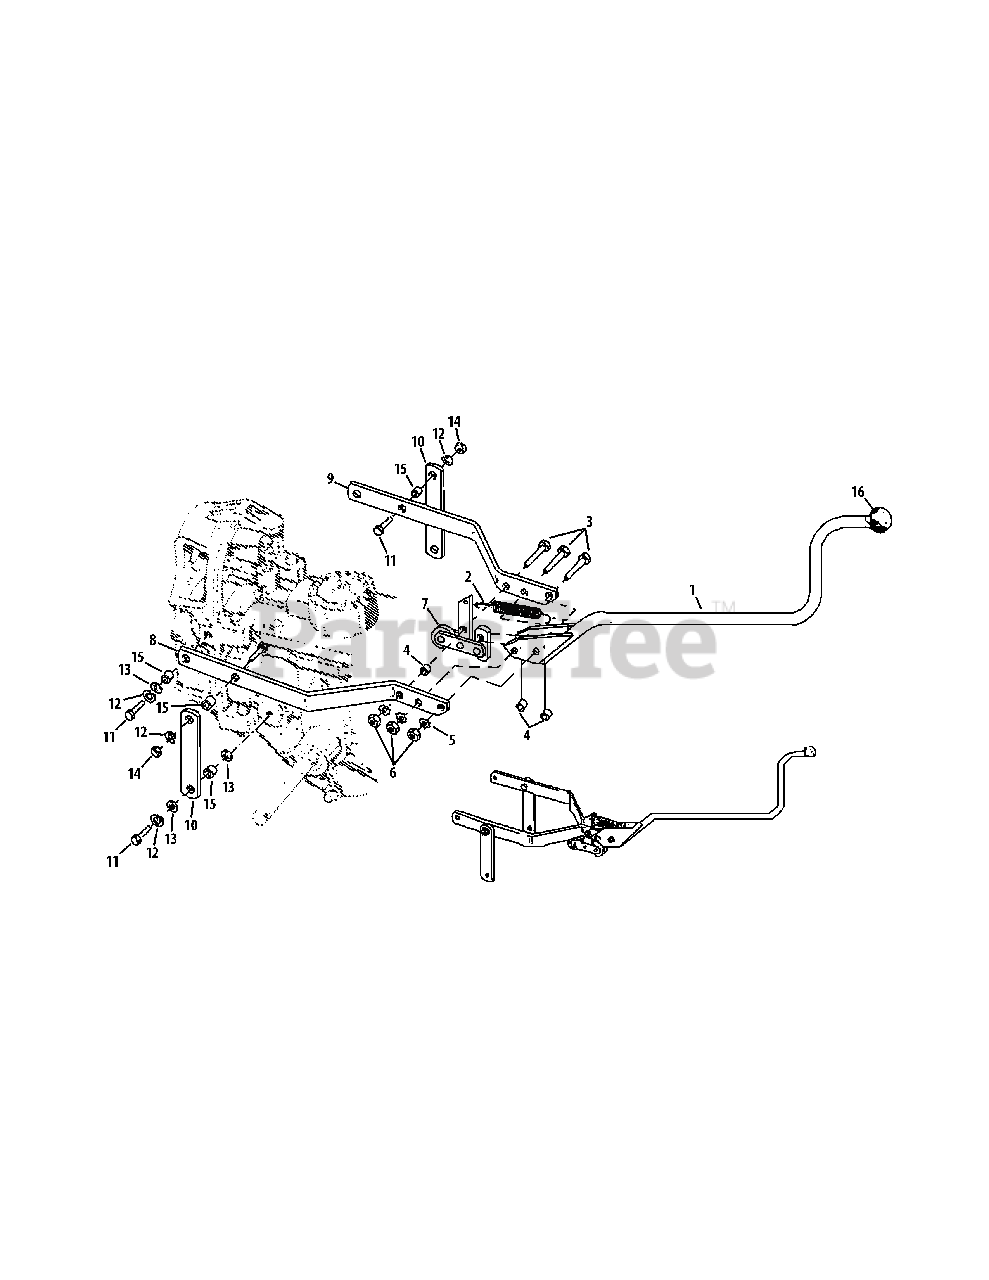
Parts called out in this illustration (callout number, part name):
1	Forward/Reverse Lever
2	Clutch Pawl Spring
3	Hex Bolt, 5/16"-18 x 1-1/2"
4	Bushing, .5 x .316 x .375
5	External Tooth Lockwasher, 5/16"
6	Hex Nut, 5/16"-18
7	Roller Assembly
8	Yoke (Left)
9	Yoke (Right)
10	Yoke Pivot Link
11	Hex Bolt, 3/8"-16 x 1"
12	Lockwasher, 3/8"
13	Flat Washer, 3/8"
14	Hex Nut, 3/8"-16
15	Bushing Spacer, .5 x .375 x .3
